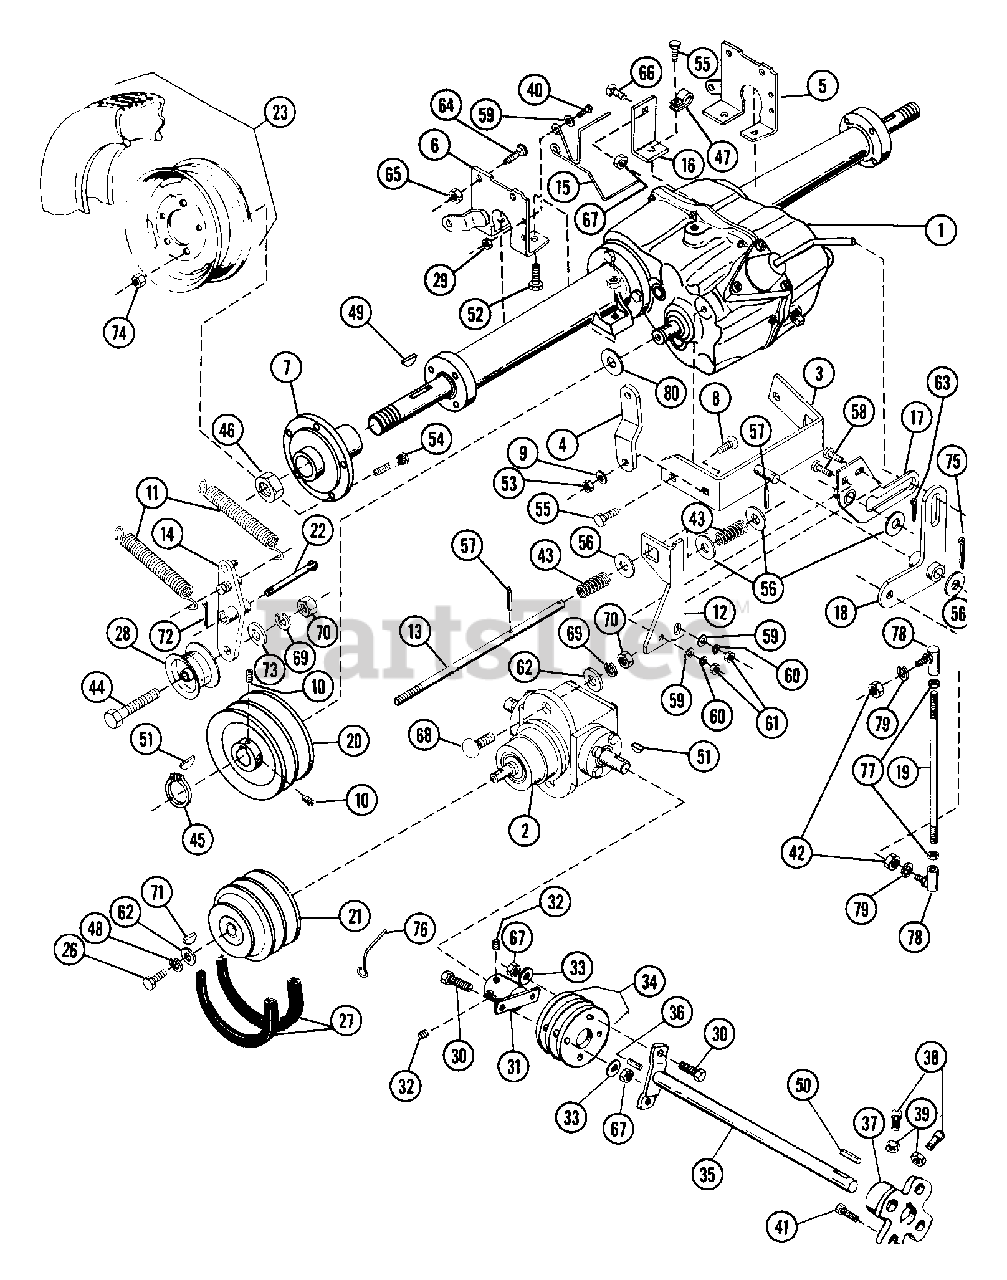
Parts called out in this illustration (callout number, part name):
1	TRANSAXLE
2	T-DRIVE HEAD ASSEMBLY
3	BRACKET
5	SUPPORT-LH AXLE
6	SUPPORT-RH AXLE
7	WHEEL HUB
8	BLT-RDHDSQNK .38-16X1.0 GR5PL
9	WSHR-FL-STL.406X.812X.065PL
10	SCR-SET .32-18X.50 SKH
11	SG-TENS .121X1.00X6.5 WLD 12
12	BRACKET
14	IDLER ARM
15	BELT FINGER
16	BRACKET
17	BELLCRANK
18	BELLCRANK
22	IDLER PIN
23	REAR TERRA TIRE 23X10.50X12
23	REAR TERRA TIRE
23	WHL 12X8.50
26	BLT-HEX .31-18X.75 PL GR5
27	V-BELT, 5L-RAW EDGE (SET)
28	IDLER-FLAT 3.218X.38
29	NUT-LK-CTR .250-20 PL
30	BLT-HEX .31-18X1.25 PL GR2
31	COUPLING
32	SCR-SET .32-18X.38 SKHCUPNL OH
33	WSHR-FL-STL.344X.688X.065PL
34	SPACER COUPLING
35	DRIVE SHAFT ASSEMBLY
36	PIN-ROLL .313X2.00
37	HOUSING AND BUSHING ASSEMBLY
38	SCR-SET .32-18X1.00 SKHCUP
39	NUT-JAM .312-18 PL
40	BLT-HEX .25-20X.75 PL GR2
41	BLT-HEX .38-16X1.25 PL GR5
42	NUT-LK .312-24
43	SG-COMP .072X.687X.75
44	BLT-HEX .38-16X2.00 PL GR2
45	RG-RTNG-EXT .750X.042
46	NUT-LK-JAM 1.0-14 PL
47	J-CLAMP
48	WSHR-LK .312X.097 PL HVY
49	KEY-WDRF .25X2.125X.531
50	KEY-WDRF .188X.875X.375 SAE11
51	KEY-WDRF .188X.75X.313 SAE 9
52	BRG-BALL .750X1.50X.44
53	NUT-LK-CTR .375-16 GR A PL
54	BLT-WHL-LUG .44-20X1.38 DANA
55	BLT-SCRHFWH .38-16X.75 PL
56	WSHR-FL-STL .531X1.062X.095 PL
57	PIN-ROLL .125X1.00
58	BLT-HEX .25-20X.50 PL GR2
59	WSHR-FL-STL.312X.734X.065PL
60	WSHR-LK .250X.077 HVY PL
61	NUT-HEX .250-20 PL
62	WSHR-FL-STL .38X.875X.083 PL
63	PIN-COTR .12X.75 PL
64	BLT-RDHDSQNK .50-13X1.25 PL
65	NUT-LK .50-13 PL
66	BLT-RDHDSQNK .31-18X1.00 PL
67	NUT-LK .312-18 GR A PL
68	BLT-RDHDSQNK .38-16X1.25 PL
69	WSHR-LK .375X.115 HVY PL
70	NUT-HEX .375-16
71	KEY-WDRF .188X.625X.25 SAE 61
72	PIN-COTR .12X1.0 PL
73	WSHR-FL-STL .438X1.0X.083 PL
74	NUT-LUG .437-20 YWZC
75	PIN-COTR .15 X 1.0 PL
76	BELT FINGER
77	NUT-JAM .312-18 PL
78	BALL JOINT
79	WSHR-LK .312X.097 PL HVY
80	WSHR-FL-STL .781X2.000X.059
81	NUT-LK TOP .375-16 GR C YWZC
82	PIN-COTR .12X1.50 PL
